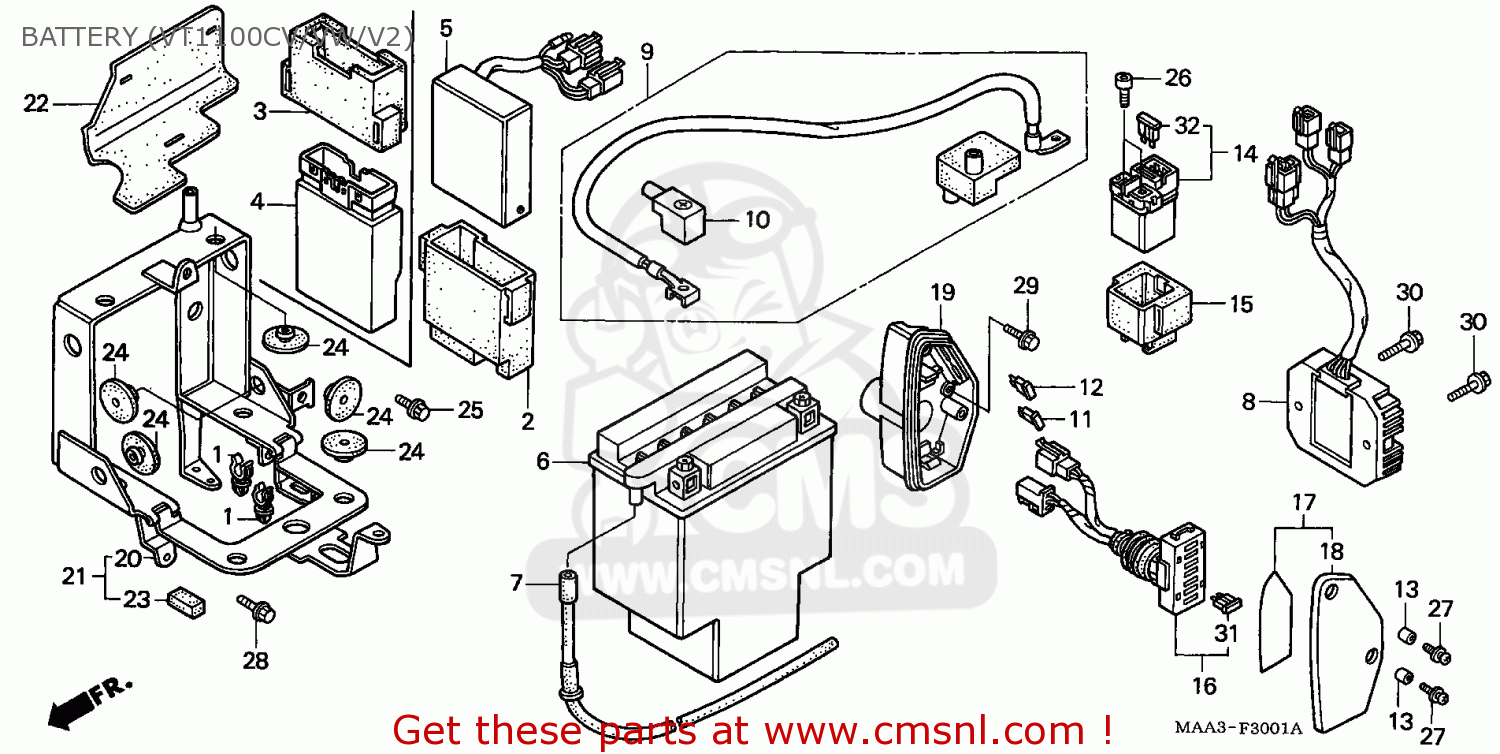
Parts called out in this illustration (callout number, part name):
1	CLIP,THROT WIRE
2	CUSHION,SPARK UNI
5	UNIT COMP,SPARK
6	BATTERY HYB16A-A
7	TUBE,BAT BREATHER
8	REG RECT ASSY
9	CABLE,START BAT
10	COVER,BAT TERMINA
11	FUSE,F10 (LITTEL)
12	FUSE,F30 (LITTEL)
13	COLLAR,FR.WINKER
14	SW ASSY,START MAG
15	RUBBER,SHOCK
16	FUSE PLATE ASSY
17	COVER COMP,FUSE B
18	COVER,FUSE BOX
19	PLATE,FUSE BOX
21	BOX COMP.,BATT
22	COVER,BATTERY
23	RUBBER
24	RUBBER,BAT.BOX
25	BOLT SPL 6X12
26	BOLT,SOCKET,5X9
27	SCREW-WASHER,5X12
28	BOLT,FLANGE,6X10
29	BOLT,FLANGE,6X16
30	BOLT,FLANGE,6X28
31	FUSE,F10 (LITTEL)
32	FUSE,F30 (LITTEL)
